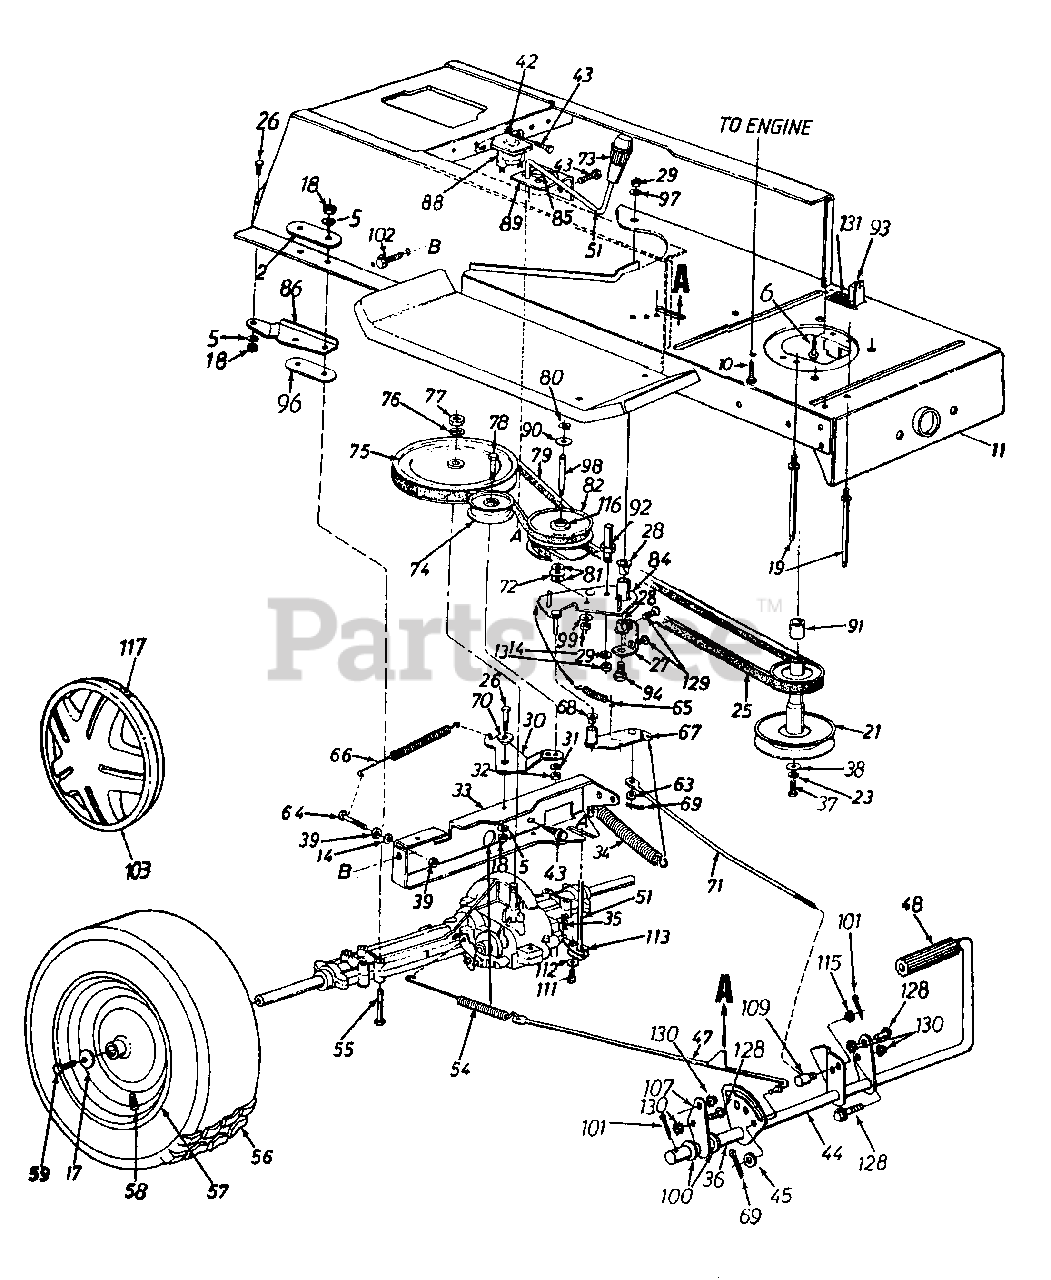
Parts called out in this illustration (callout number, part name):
2	Transaxle Mtg. Brkt.
5	L-Wash. 5/16" I.D."
10	Hex TT-Tap Scr. 3/8-16 x1.5" Lg.
13	Hex Nut 1/4-20 Thd. (Gr. 5)
14	L-Wash. 1/4" I.D."
17	Bell-Wash. .345" I.D. x .88"
18	Hex Nut 5/16-18 Thd. (Gr. 5)
19	Belt Guard Stud 4.75" Lg.
21	Engine Pulley
22	Fl-Wash. 7/16" I.D. x 1.25"
23	L-Wash. 7/16" 1.13.
24	Hex Bolt 7/16-20 x 1.50" Lg.
25	Variable-Speed Belt
26	Hex Bolt 5/16-18 x .75" Lg.
27	Bearing Shaft Bracket Ass'y.
28	Flanged Nyliner Brg. 5/8" I.D. x .88" Lg.
29	Hex Nut 3/8-24 Thd.
30	Idler Bracket
31	L-Wash. 3/8" I.D.
32	Hex Nut 3/8-24 Thd.
33	Transaxle Support Brkt.
34	Ext. Spring .94" O.D. x 7.58"
35	Inter. Cotter Pin
36	Spacer.63" I.D.
39	Hex Nut 1/4-28 Thd.
40	Hex AB-Tap Scr. 1/4" x .62" Lg.
42	Ext. L-Wash. 1/4" I.D.
43	Hex Wash. S-Tap Scr.1/4-20 x .50" Lg.
47	Brake Rod Ass'y.
48	Foot Pad
51	Shift Lever Ass'y.
54	Ext. Spring .59" O.D. x 7.08"
54	Ext. Spring 7.33" Lg.
55	Hex Bolt 5/16-18 x 3.5" Lg.
55	Hex Bolt 5/16-18 x 3" Lg.
58	Air Valve
59	Hex Bolt 5/16-24 x .75" Lg.
63	Fl-Wash. .34" I.D. x .68" O.D.
64	Hex Bolt 1/4-28 x 1.25" Lg.
65	Ext. Spring
66	Ext. Spring .62" O.D. x 6.12"
67	Variable Speed Torque Brkt. Ass'y.
68	Flanged Bearing
69	Cotter Pin 3/32" Dia.
70	Shoulder Spacer.27" Lg.
71	Speed Control Link
72	Truss Bearing .56 Dia. x 1.25"
73	Shift Knob
74	Fl-Idler Pulley 3.12" Dia.
75	V Pulley
76	Bell-Wash. .56" I.D. x 1.125"
77	Hex Jam Nut 5/16-18 Thd.
78	Hex Bolt 3/8-24 x 1.75" Lg.
79	Variable Speed Belt
80	Snap Ring .56" Dia.
81	Fl-Wash.
82	Variable Speed Pulley Ass'y.
84	Variable Speed Brkt. Ass'y.
85	Comp. Spring-Clip
86	Axle Support Brkt.-R.H.
86	Axle Support Brkt.-L.H.
88	Solenoid
89	Shift Lever Bracket
90	Teflon Washer.565" I.D.
91	Spacer 1" I.D. x 1.25" Lg.
92	Belt Keeper 3" Lg.
93	Safety Switch (Clutch)
94	Shld. Bolt 3/8-24 x 3.12" Lg.
97	Bell-Wash. .38" I.D. x .88"
98	Shaft .56" Dia. x 3.875" Lg.
99	Bell-Wash. .39" I.D. x 1.12"
100	Fl-Wash. .64" I.D. x .94"
101	Cotter Pin 1/8" Dia. x 1.25"
102	Hex Wash. Hd. Scr. 5/16-18 x .62"
103	Hub Cap
107	Pedal Bracket
109	Ferrule
111	Hex Bolt 1/4-28 x .50" Lg.
112	Bell-Wash. .265" I.D. x .75"
113	Shift Lever Link Ass'y.
115	Fl-Wash. .385" I.D. x .62"
116	Needle Brgs. (2 Req'd.)
117	Spring Clip
128	Hex Wash. TT-Tap Scr. 5/16-18x .75"
129	Hex Wash. AB-Tap Scr. 5/16-18x .75"
130	Hex Sems Nut 5/16-18 Thd.
131	Spring Switch
